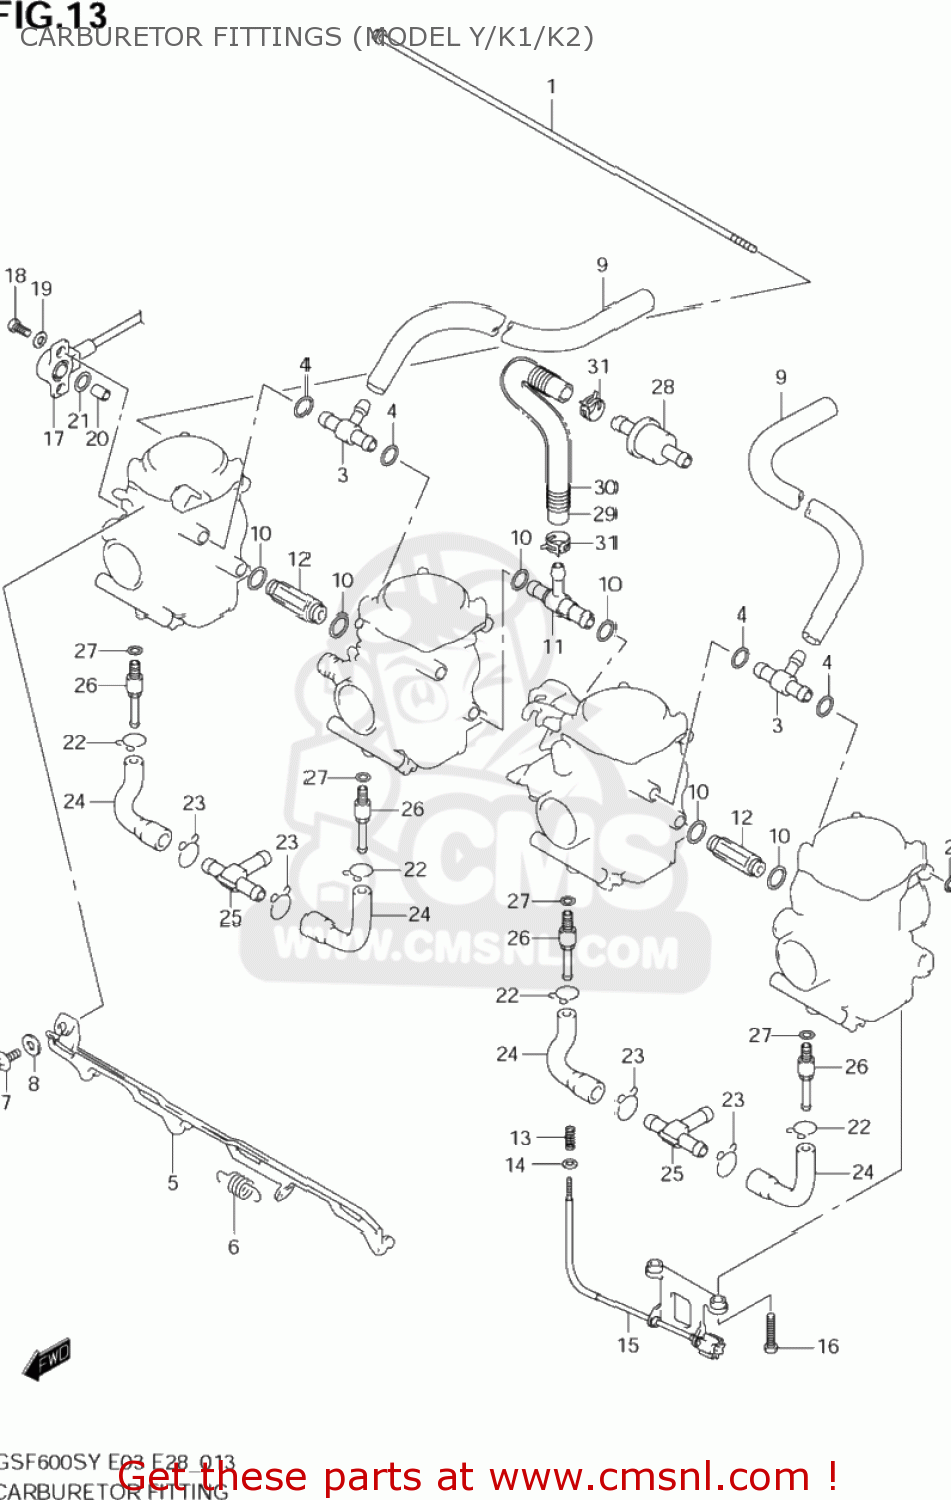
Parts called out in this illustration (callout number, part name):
1	BOLT
2	NUT
3	JOINT
4	O RING
5	LEVER,STARTER
6	SPRING
7	SCREW
8	WASHER
9	HOSE(7X11X600)
10	O RING
11	JOINT
12	JOINT
13	SPRING
14	WASHER
15	ADJUSTER
16	SCREW
17	SENSOR,THROTTLE
18	SCREW
19	WASHER
20	COLLAR
21	O RING
22	CLIP
23	CLIP
24	HOSE
25	JOINT
26	JOINT
27	O RING
28	STRAINER COMP,FUEL
29	HOSE,FUEL
30	SPRING
31	CLIP
